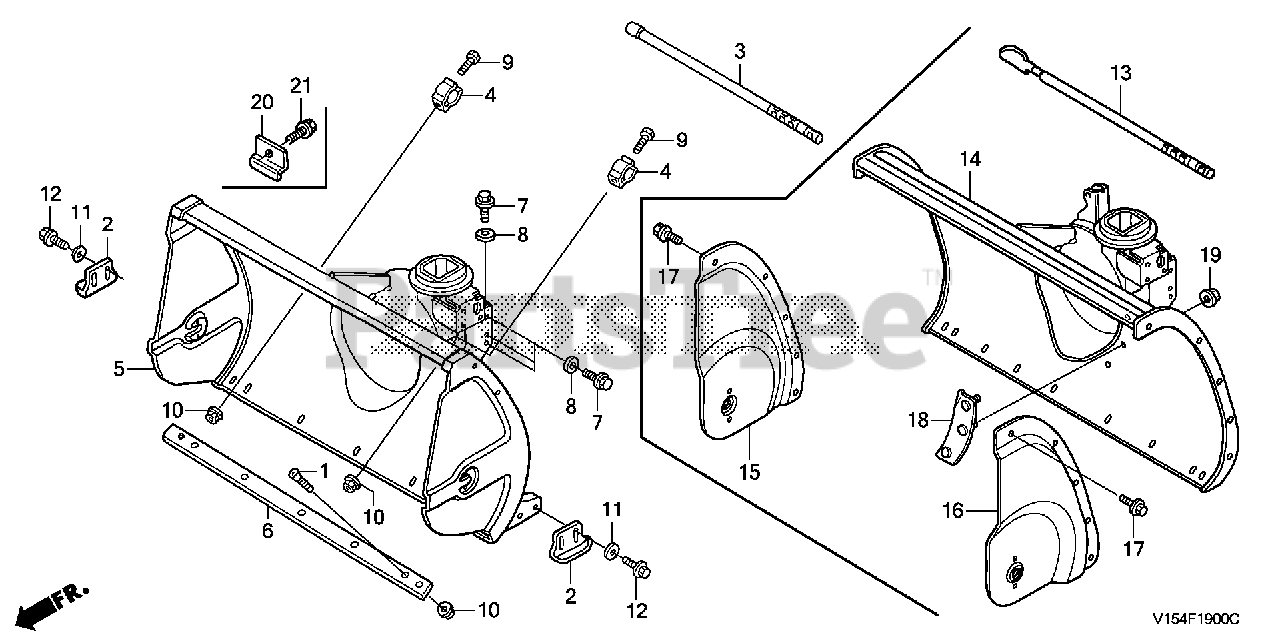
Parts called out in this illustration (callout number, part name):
1	BOLT, LOCK STRIKER
2	SKID, AUGER
4	BRACKET, SNOW DROP BAR
5	HOUSING, AUGER
6	GUARD, AUGER HOUSING
9	BOLT, HEX. (8X16)
10	NUT, FLANGE (8MM)
11	WASHER, PLAIN (8MM)
12	BOLT, FLANGE (8X20)
13	BAR, SNOW DROP
18	GUARD, AUGER (UPPER)
19	NUT, FLANGE (M8X1.25) (SELF-LOCK)
20	GUIDE, ROLLING
21	BOLT, FLANGE (10X16)
